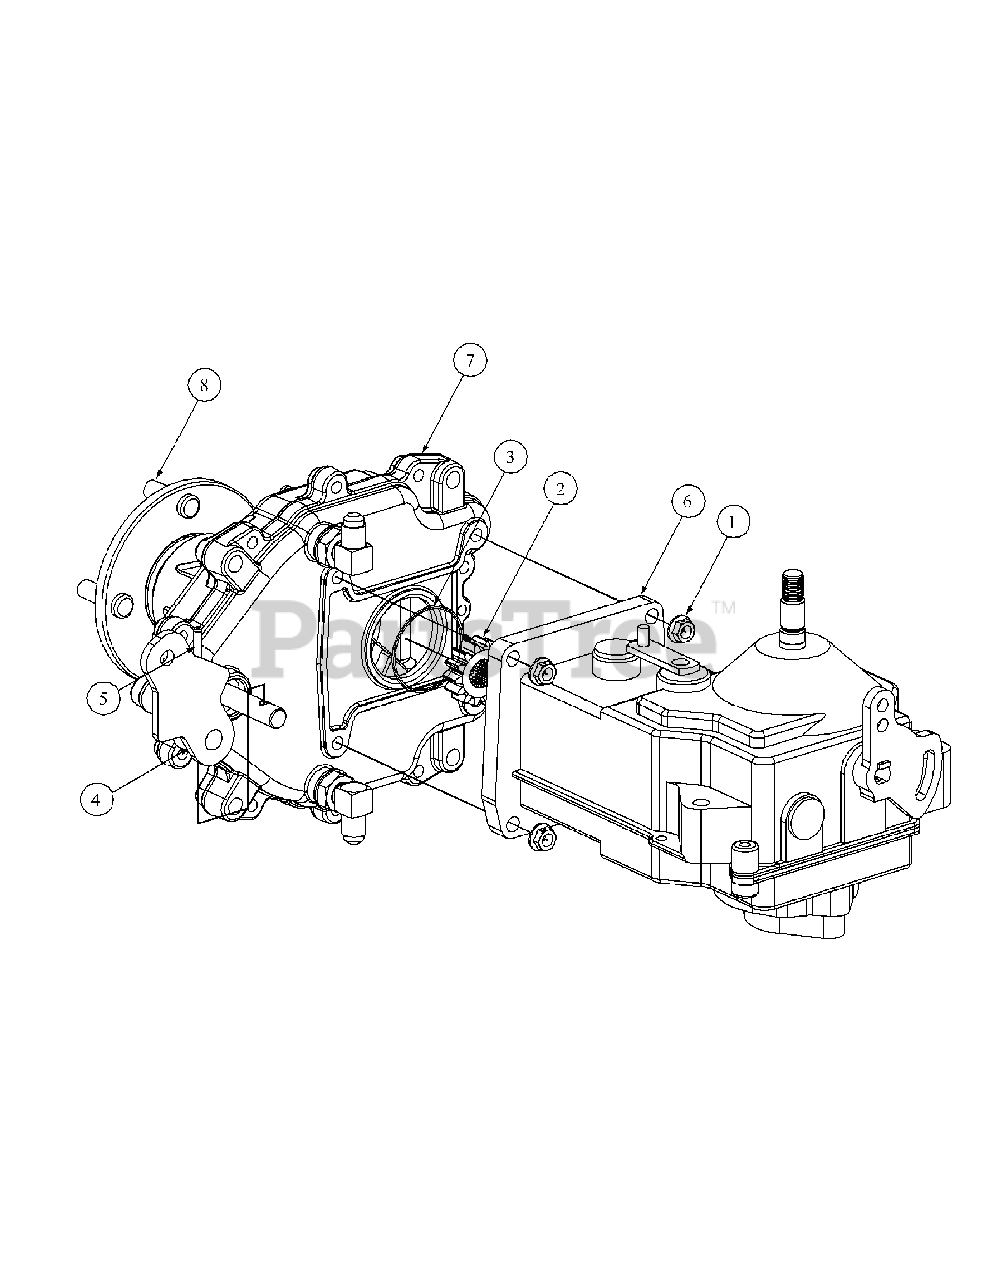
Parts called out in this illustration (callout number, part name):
1	Lock Nut, Hex Flange 5/16-18
2	Gear, Spur, 14T
3	O-Ring, 2.00 x .070
4	Lever, Brake, Park
5	Pin, Spirol, 3/16 x 1.25 HD
6	Pump, Hydro
7	Transmission Assembly
8	Rib Neck Stud
